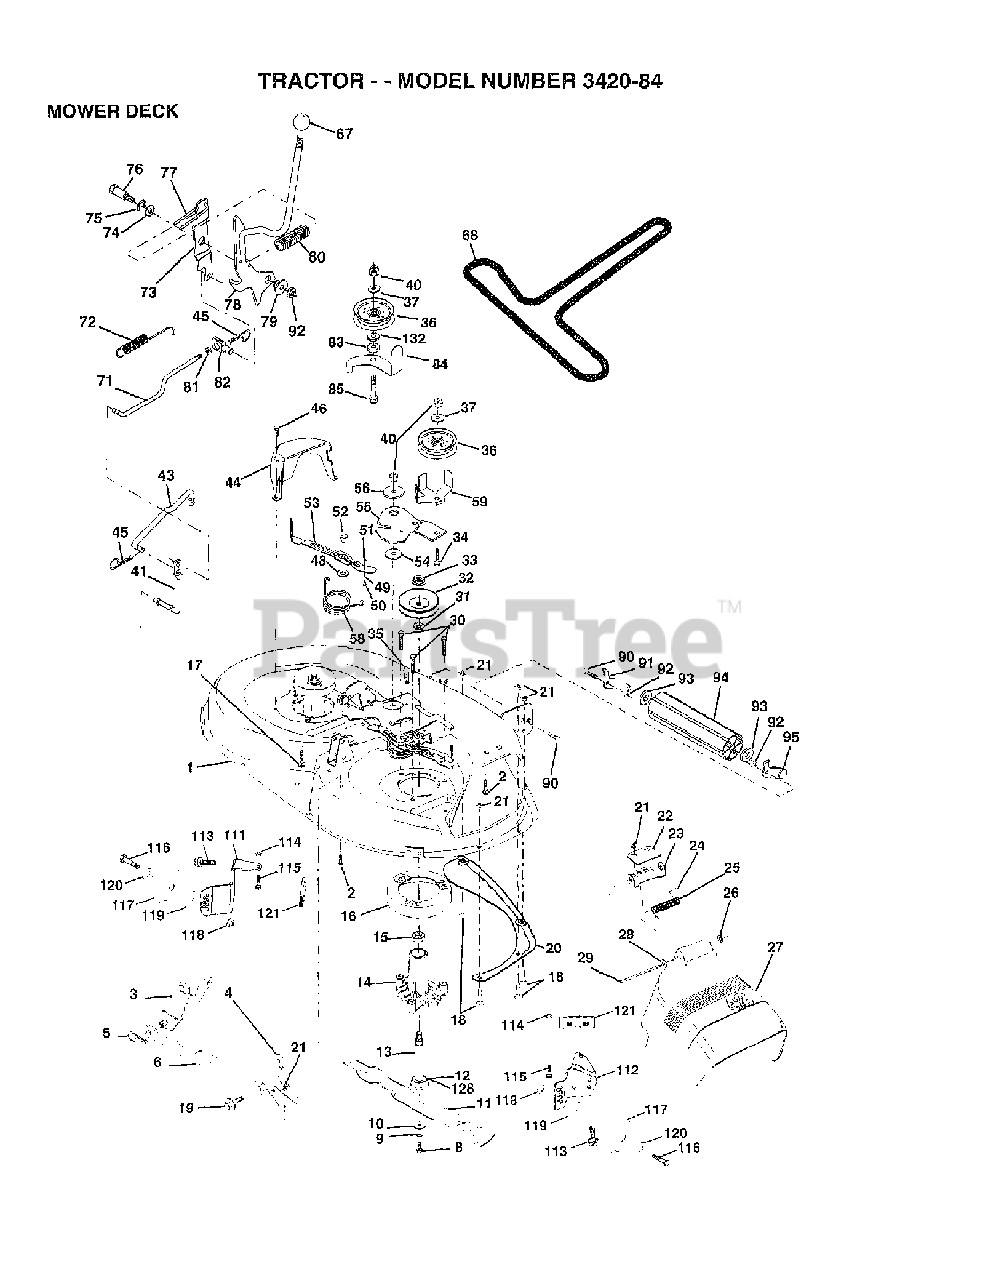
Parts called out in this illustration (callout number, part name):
2	BOLT
3	BRKT ASM SWAY BAR
4	BRKT DECK SW BAR
5	RETAINER SPRING
8	BLADE BOLT
10	WASHER.BLADE
11	BLADE 42" LOW-LIFT VENT DECK
12	BEARING.BALL.#6204.(MANDREL)
13	SHAFT ASM VENT
14	HSG MANDREL
17	BOLT
18	BOLT
19	BOLT SHD 5/16-18
20	BAFFLE.VORTEX
21	LOCKNUT
23	DEFLECTOR BRACKET
24	CAP-SLEEVE LT
25	DEFLECTOR SPRG T
27	SHIELD.DEFLECTOR.MOWER.42".BLK
28	WASHER
29	ROD.HINGE
30	Hex Washer Head Bolt, .313-18 X 1.19
31	WASHER
32	PULLEY/MANDREL
34	BOLT
35	FASTENER.XMAS.TREE
36	IDLER-FLAT GT
40	LOCKNUT
41	PIVOT ROD
43	CLUTCH ROD
44	MANDREL GUARD LH
46	SCREW.1/4-20X5/8
50	BOLT
52	BOLT, SHOULDER LT
55	ARM IDLER 42" MOWER LT/YT
59	GUARD, BELT
67	PIGTAIL, LIGHT
68	V-BELT TRIPATH
72	RETURN SPRING
73	ARM CLUTCH SECONDARY
75	RING CLIP
78	Poulan TBD
79	BUSHING.FLANGE.E-RING.GROOVE
80	SPRING-CLUTCH
81	NUT
82	TRUNION T
84	KEEPER.BELT.IDLER
90	BOLT
91	Roller Bracket Assembly, LH
92	NUT
94	MANUAL, OPERATOR
113	Screw, Lt
116	BOLT
117	GUAGE WHEEL GT
118	LOCKNUT
119	WASHER
121	BRACKET.EXTRUDED.GAGE.WHEEL
128	WASHER FELT
132	WASHER GT
